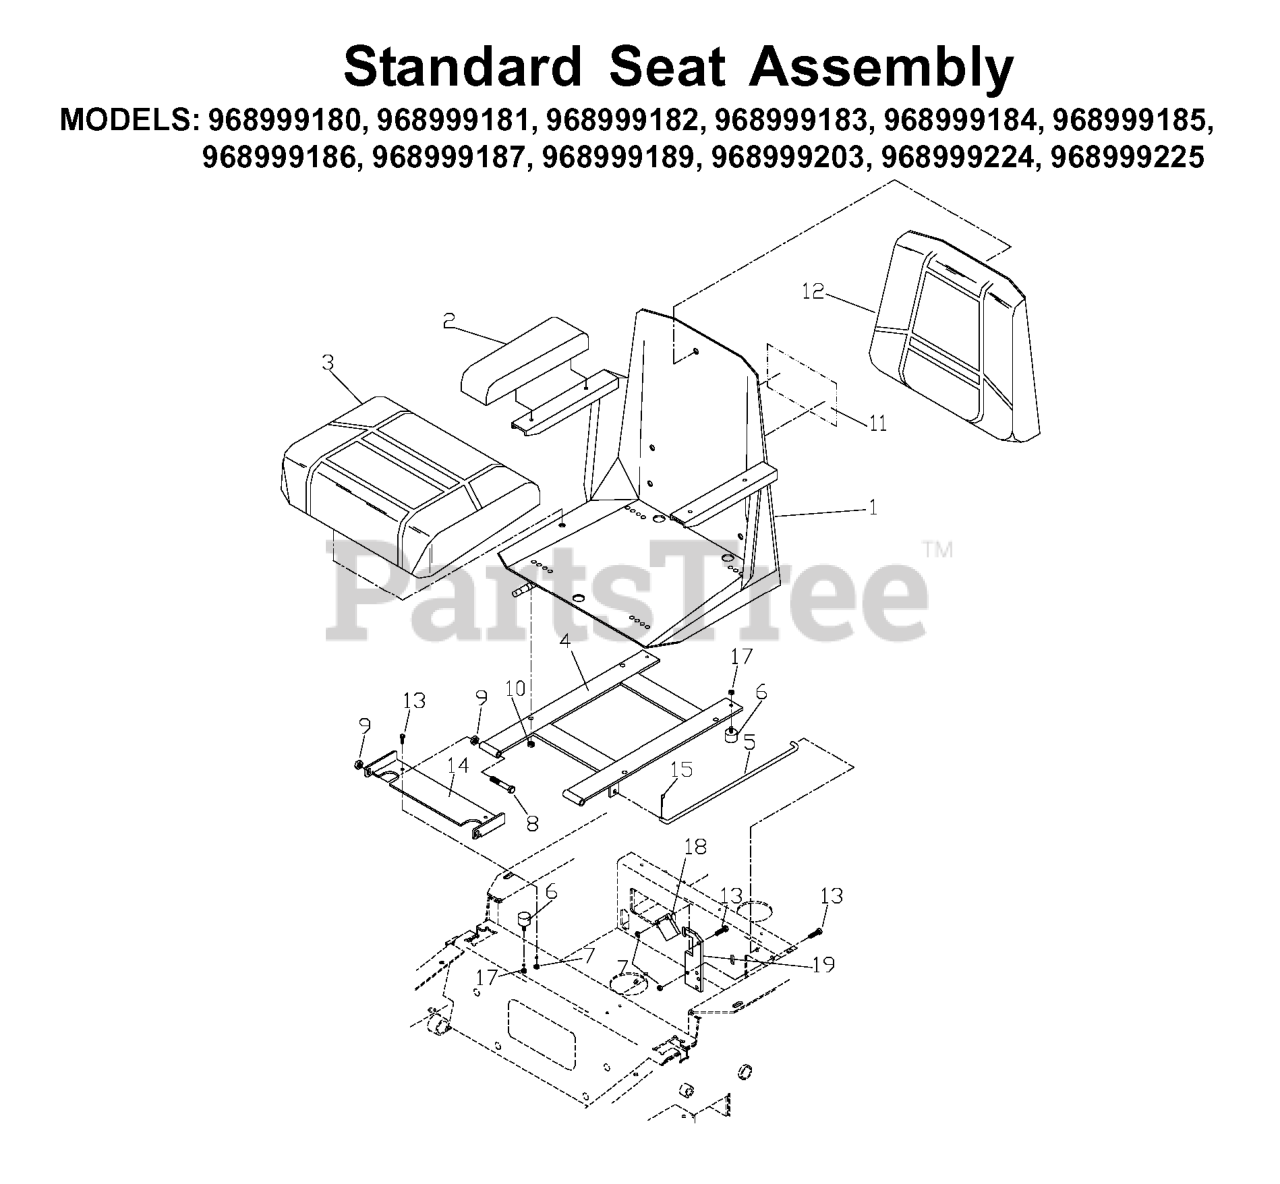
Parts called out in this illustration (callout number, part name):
1	SEAT, COMPLETE
2	ARM REST CUSHIONS/PAIR
3	SEAT CUSHION W/SWITCH
4	SEAT MOUNT
6	STUD/PLATE MOUNT
7	NUT 1/4C CENTER LOCK
8	HCS 3/8C X 3
9	NUT 3/8C CENTERBLOCK
10	NUT 5/16 NYLOC
11	DECAL, CROWN H
12	SEAT, BACK CUSHION
13	HCS 1/4C X 3/4 HCS
14	SEAT BRKT W/DECAL
15	RP_COTTER PIN 1/8 X 3/4
16	SEAT RAILS
17	NUT.1/4-20.HEX.NYLOC.ZD
18	SEAT LATCH
19	SEAT LATCH BASE
21	SEAT SWITCH
539105294	SEAT RAILS
